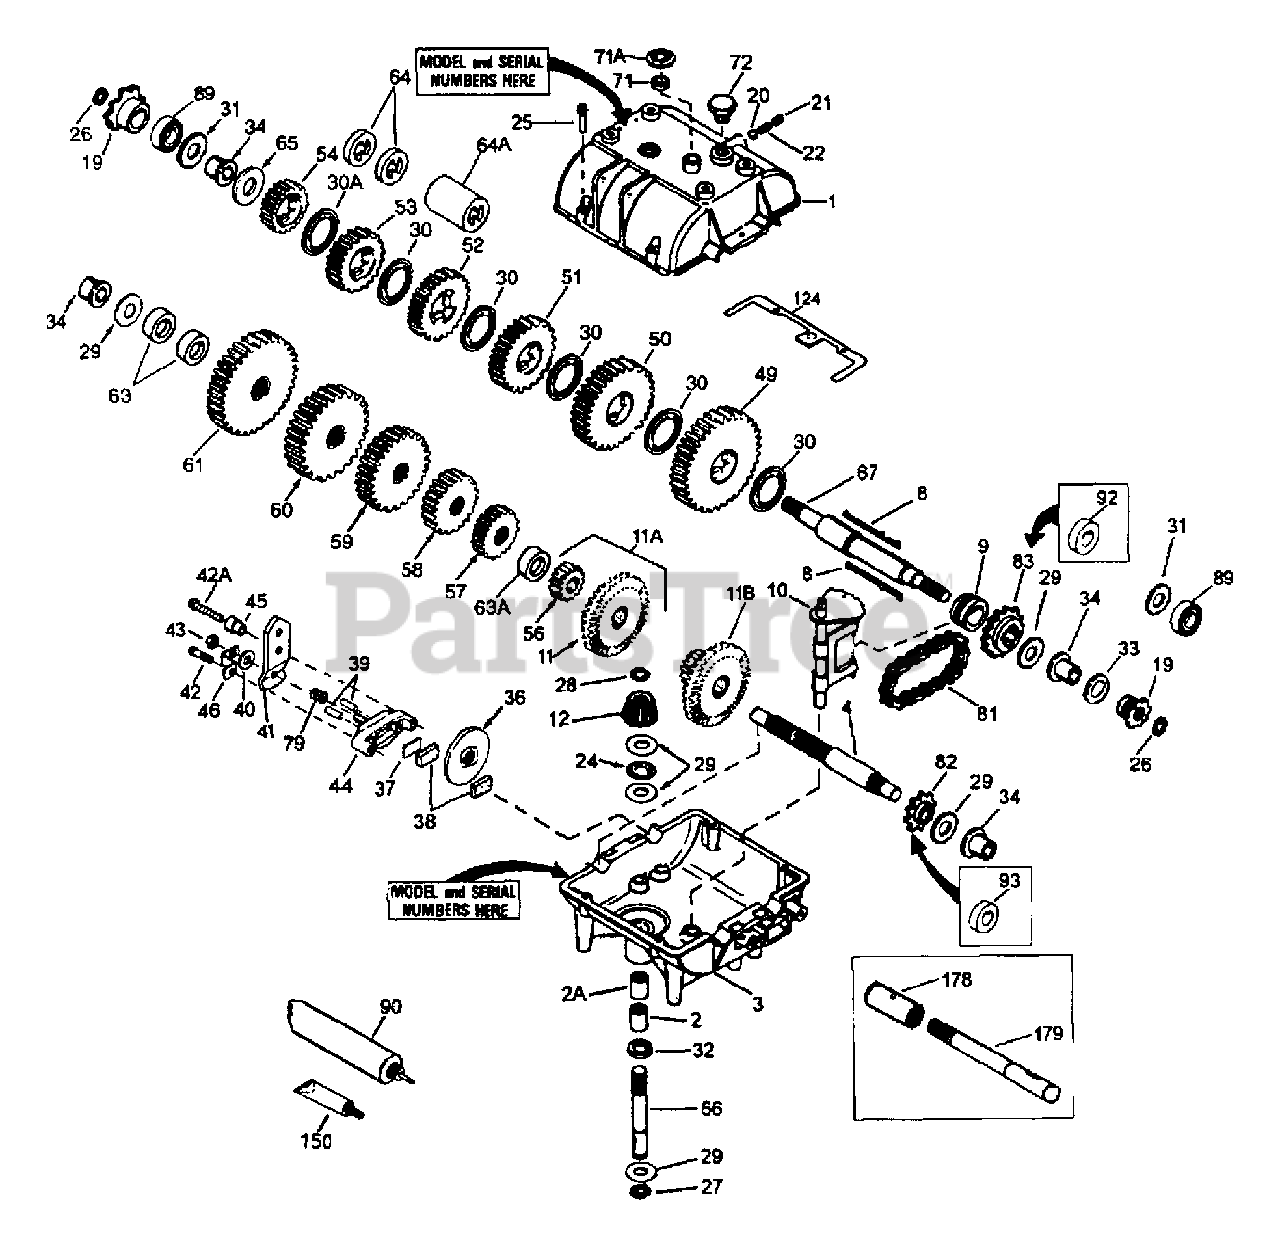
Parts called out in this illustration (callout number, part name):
1	Case, Transmisson
2	Needle Bearing Grease Spec
2A	Needle Bearing
3	Case, Transmission
8	Shift Key
9	Shift Collar
10	Shift Rod & Fork
11	Bevel Gear (42 teeth)
12	Bevel Pinion (14 teeth-steel)
20	Steel Ball, 5/16" dia.
21	Set Screw, 3/8-16 x 3/8"
22	Spring
24	Thrust Bearing
25	Screw, 1/4-20 x 1-1/4" (6)
27	Retaining Ring
28	Retaining Ring
29	Washer (6)
30	Washer (5)
32	"O" Ring
34	Flanged Bushing
49	Spur Gear (37 teeth)
50	Spur Rear (35 teeth)
51	Spur Gear (32 teeth-steel)
52	Spur Gear (30 teeth)
53	Spur Gear (25 teeth)
56	Spur Gear (12 teeth-steel)
57	Spur Gear (15 teeth)
58	Spur Gear (18 teeth-steel)
59	Spur Gear (20 teeth)
60	Spur Gear (25 teeth)
65	Washer
66	Input Shaft (3-11/16" long)
67	Shifter & Brake Shaft
71	Square Cut Ring
72	Threaded Plug (Shipping only, not used)
81	Roller Chain (No. 41 chain, 24 links)
82	Sprocket (9 teeth)
83	Sprocket (18 teeth)
90	Grease (32 oz. bottle Bentonite grease)
150	Gasket Eliminator (Loctite #515)
178	Coupling
179	Connector Shaft
